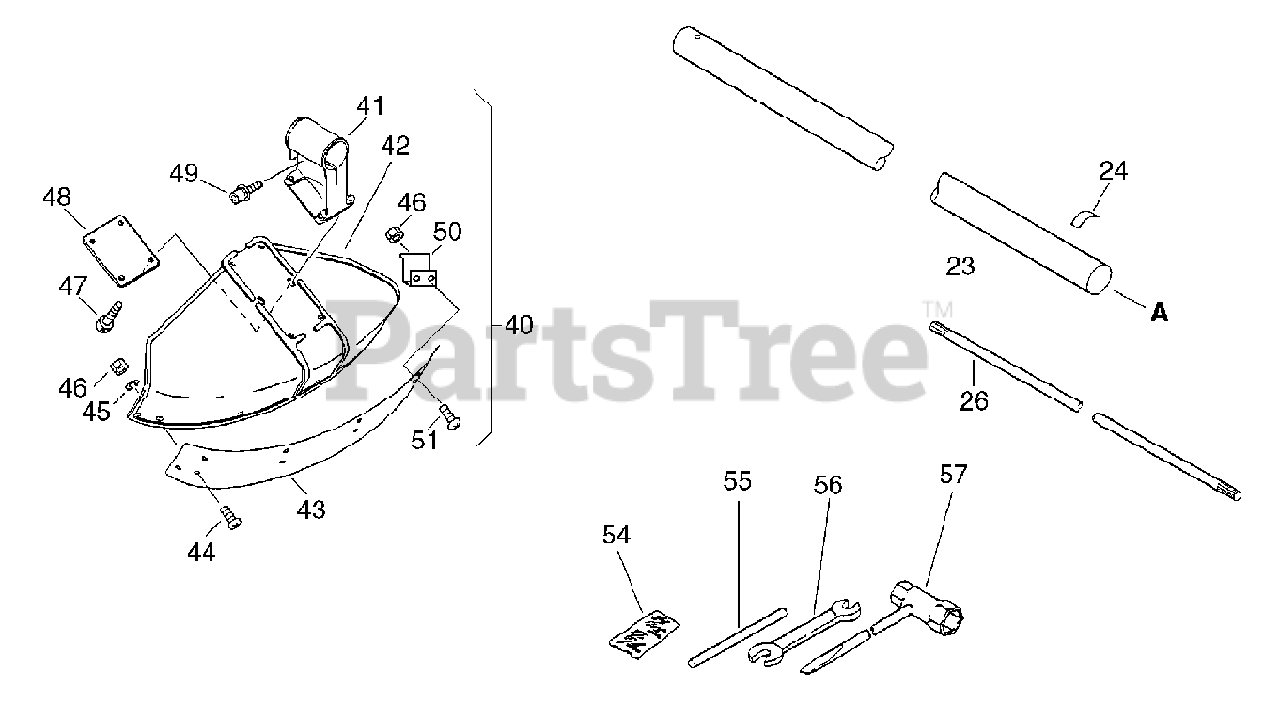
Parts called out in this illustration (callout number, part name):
23	Housing Ass'y d,Sft.
24	Label, Caution
26	Shaft, Drive
40	Shield, Assy
41	Bracket, Shield
42	Shield, Blade
43	Plate, Shield
44	Screw 5*18
46	Nut 5
47	Screw 5*14
48	Plate, Shield
49	Bolt 5*25 (W/W,SW)
51	Screw 5*12
54	Pin 2*22 (W/Pouch)
55	Locking Tool
56	Spanner 8*10
57	Tool,Wrench
